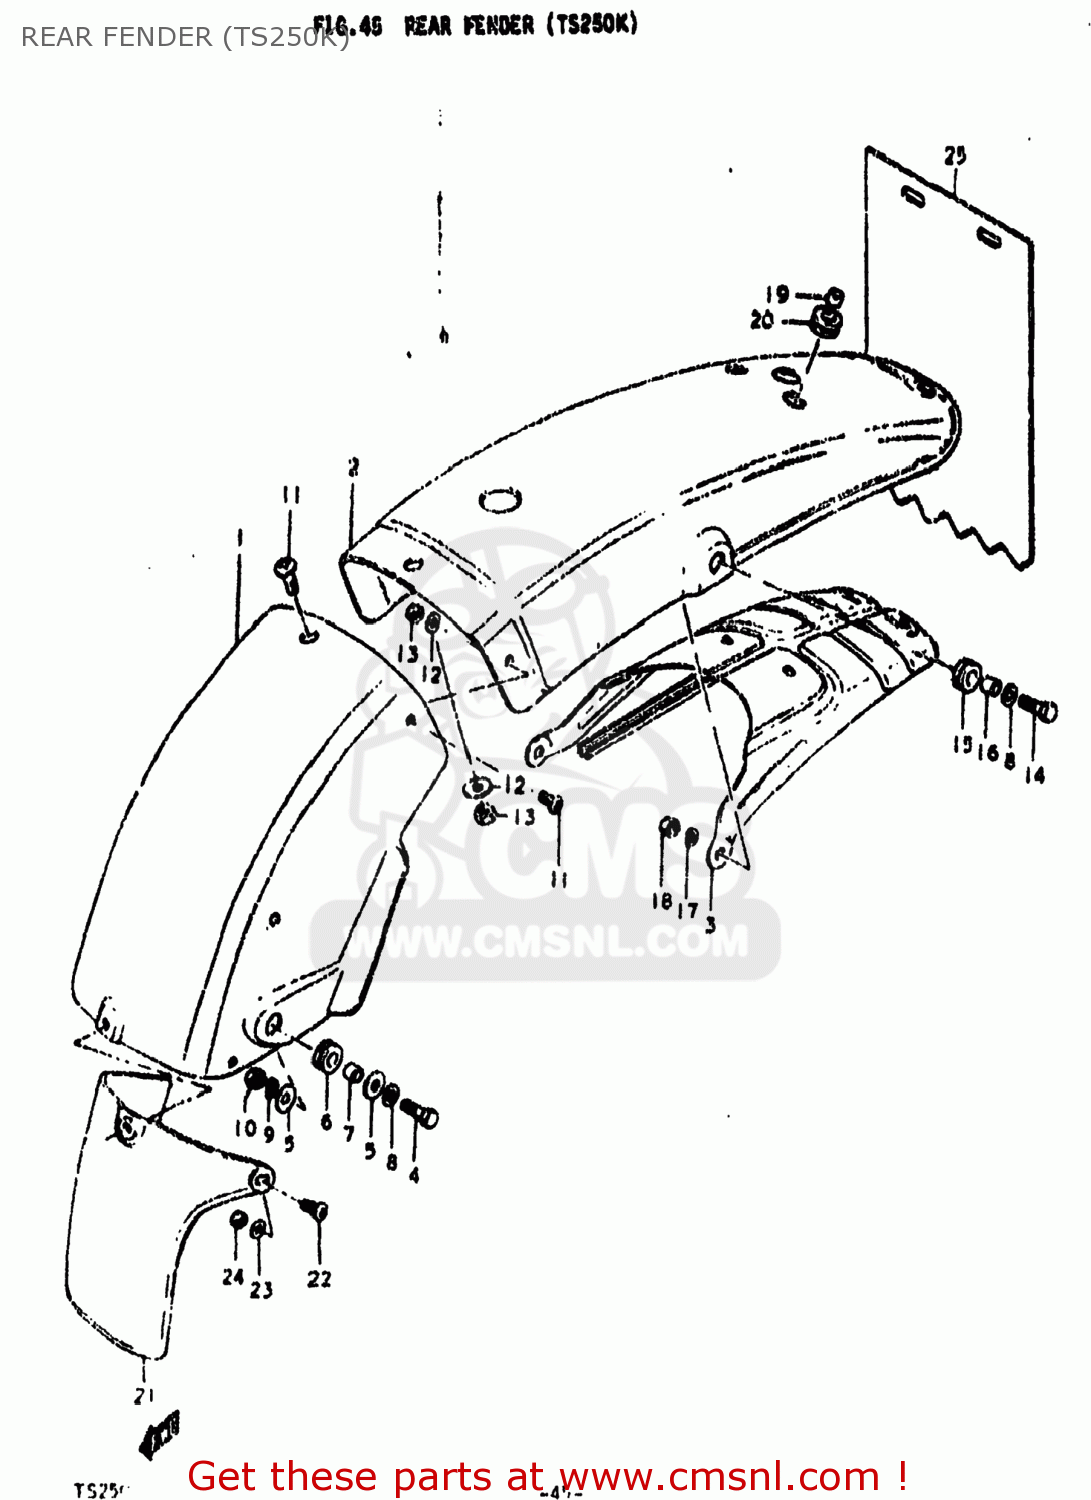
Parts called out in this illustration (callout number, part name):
1	FENDER,REAR
2	FENDER,REAR
3	REINFORCEMENT,REAR FENDER
4	BOLT
5	WASHER (6.5X20X1.2)
6	CUSHION
7	SPACER(6.1X9X7.5)
8	WASHER
9	LOCK WASHER
10	NUT
11	SCREW
12	WASHER
13	NUT
14	BOLT
15	CUSHION
16	SPACER(6.1X9X7.5)
17	LOCK WASHER
18	NUT
19	SPACER(6.1X9X7.5)
20	CUSHION
21	MUD GUARD,REAR FENDER
22	SCREW
23	WASHER
24	NUT
25	MUD GUARD,REAR FENDER
